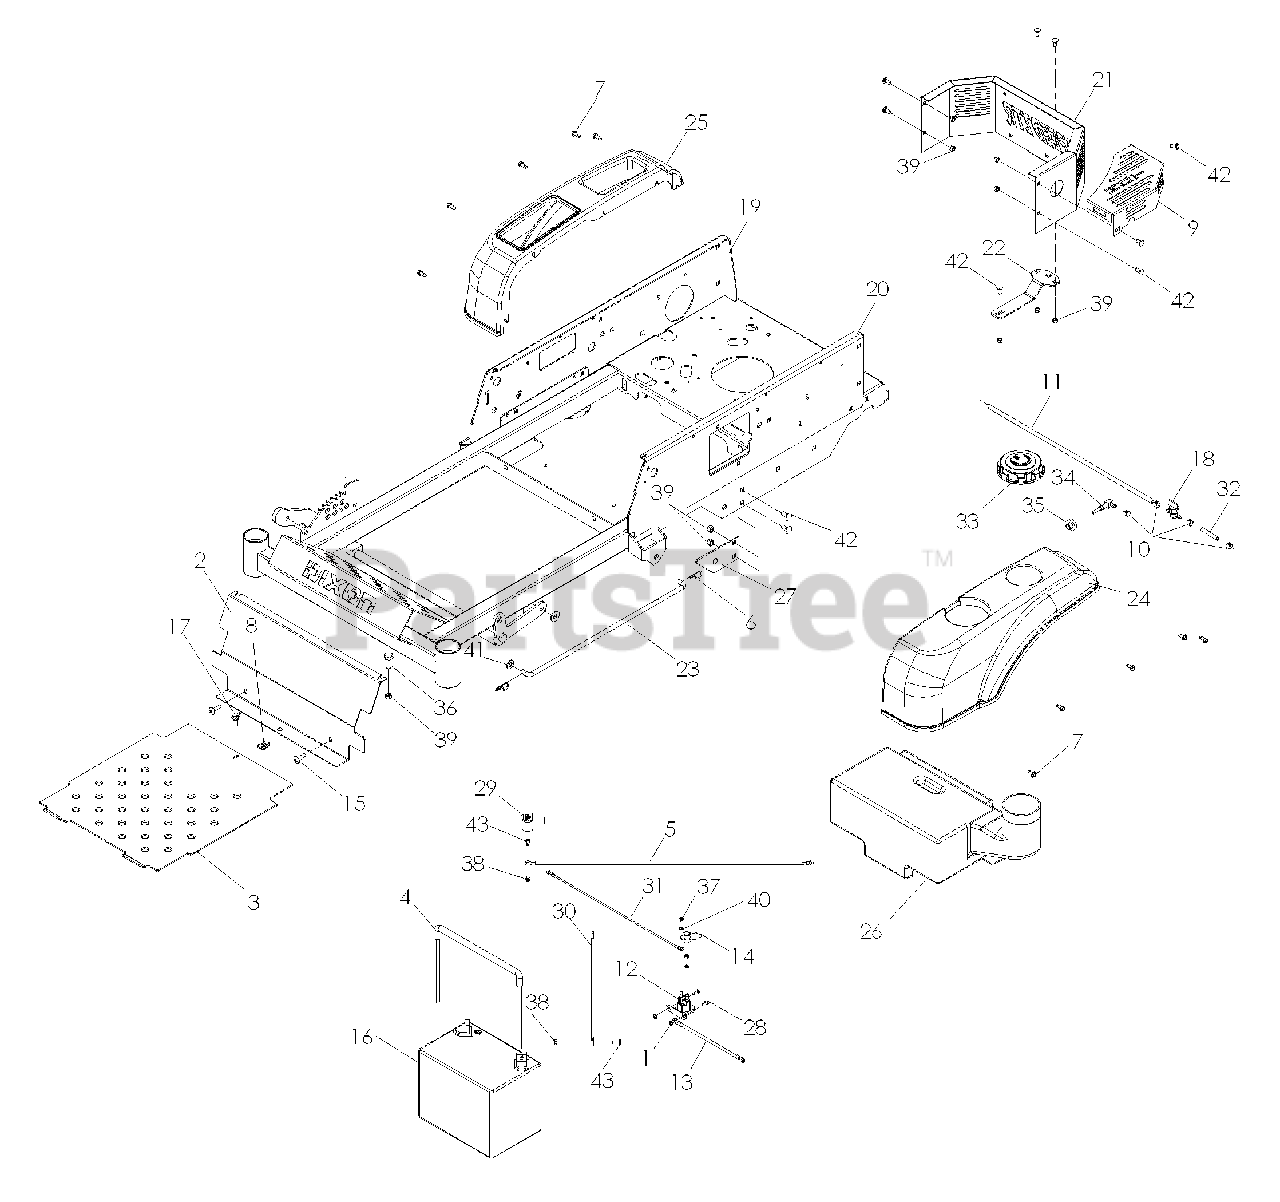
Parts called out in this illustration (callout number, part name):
1	WASHER 1/4 EXTLW STAR ZD
2	FRONT PANEL, W/DECALS
3	FOOT PLATE, W/DECALS
4	BATTERY TIE DOWN ASSEMBLY
5	BATTERY CABLE
6	PIN, COTTER 1 3/4
7	SCREW 1/4 X 5/8
8	1/4C - U TYPE RETAINER
9	HEAT SHIELD, MUFFLER
10	HOSE CLAMP
11	HOSE 1/4 X 21"
12	SOLENOID
13	BATTERY GROUND CABLE
14	TERMINAL COVER-SM
15	5/16-18X1 FLANGED SCREW
16	BATTERY, 12 V 330 AMP TBR
17	1/4-20 X 3/4 WING BOLT
18	FUEL VALVE
19	SIDE PLATE, RH
20	SIDE PLATE, LH
21	REAR GUARD SPD 30
23	ROD TRAILING ARM
24	FENDER LH
25	FENDER RH
26	FUEL TANK
27	DOUBLER PLATE
28	SCREW 1/4 X 5/8
29	TERMINAL COVER
30	NEGATIVE CABLE 20"
31	CABLE POSITIVE, LONG
32	HOSE 1/4 X 2"
33	FUEL CAP ANTI-SPLASH
34	ELBOW W/FILTER
35	TANK FITTING
36	HCS 5/16C X 3/4
37	NUT 1/4-20 JAM
38	NUT 1/4-20 NYLOC
39	NUT 5/16 NYLOC
40	WASHER 1/4 INT TOOTH
41	WASHER 1/2" FLAT
42	BOLT 5/16C X 3/4" CARRIAGE
43	HCS 1/4C X 3/4 HCS
